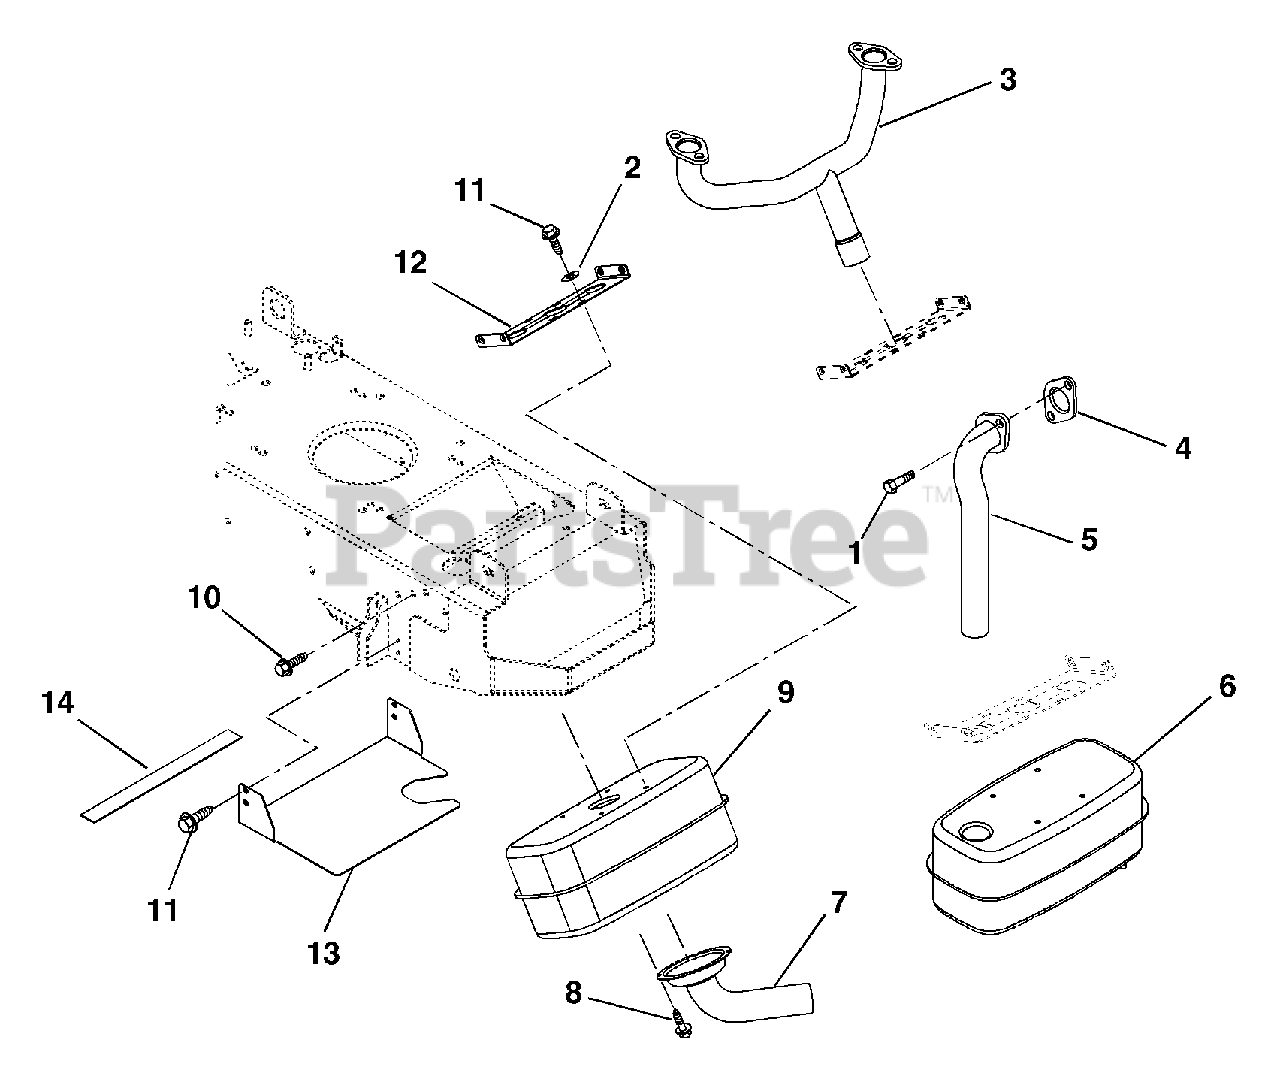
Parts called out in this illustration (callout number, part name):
1	SCR-CAP .31-18X.75 S/HD
2	@WSHR-FL-STL.250X.56X.049 YWZC
3	PIPE, EXHAUST INTEK V TWIN
4	GASKET B&S#272293
5	PIPE - EXHAUST
6	MUFFLER W/DEFLECTOR
7	DEFLECTOR - EXHAUST
8	SCR-TAP 8-32X.38 SL HWH YWZC
9	MUFFLER - EXHAUST
10	@SCR-TAP .31-18X.50 HWH TR YWZ
11	@SCR-TAP 12-24X.75 HWH YWZC
12	BRACKET - MUFFLER
13	SHIELD, HEAT
14	HEAT SHIELD- FABRIC 1X10.75
